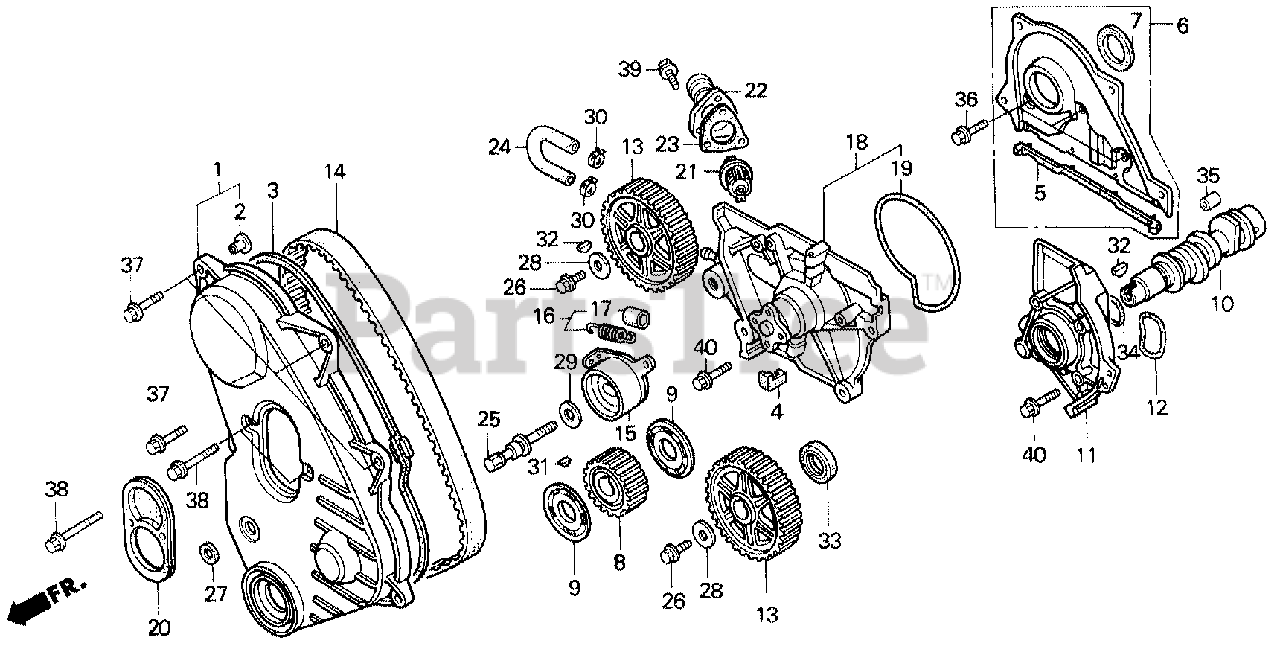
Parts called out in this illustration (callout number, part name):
1	COVER A, TIMING BELT
2	COLLAR, TIMING BELT COVER (LOWER)
3	RUBBER A, SEAL
4	RUBBER, R. BACK SEAL
5	RUBBER C, SEAL
6	COVER, RR. TIMING BELT
7	RUBBER, RR. COVER SEAL
8	PULLEY, TIMING BELT DRIVE
9	PLATE, TIMING BELT GUIDE
10	CAMSHAFT, FUEL
11	COVER, FUEL CAM
12	GASKET, FUEL CAM COVER
13	PULLEY, TIMING BELT DRIVEN
14	BELT, TIMING
15	TENSIONER, TIMING BELT
16	SPRING, TIMING BELT ADJUSTING
17	BOOT, SPRING
18	WATER PUMP
19	O-RING, WATER PUMP
20	RUBBER, WATER PUMP SEAL
21	THERMOSTAT
22	COVER, THERMOSTAT
23	GASKET, THERMOSTAT COVER (NON-ASBESTOS)
24	HOSE, WATER BYPASS
25	BOLT, TIMING BELT ADJUSTER
26	BOLT, FLANGE (8X22)
26	BOLT-WASHER (8X22)
27	RUBBER, TIMING BELT ADJUSTER
28	WASHER, SPECIAL (28X8.5X4.0)
29	WASHER (10.3X25)
30	CLAMP, CANISTER HOSE
31	KEY (4.5X11.0)
32	KEY (25.4X13)
33	OIL SEAL (29X45X8)
34	O-RING (64X2.3)
35	PIN, DOWEL (10X12)
36	BOLT, FLANGE (6X12)
37	BOLT, FLANGE (6X16)
38	BOLT, FLANGE (6X20)
39	BOLT, FLANGE (6X25)
40	BOLT, FLANGE (8X35)
